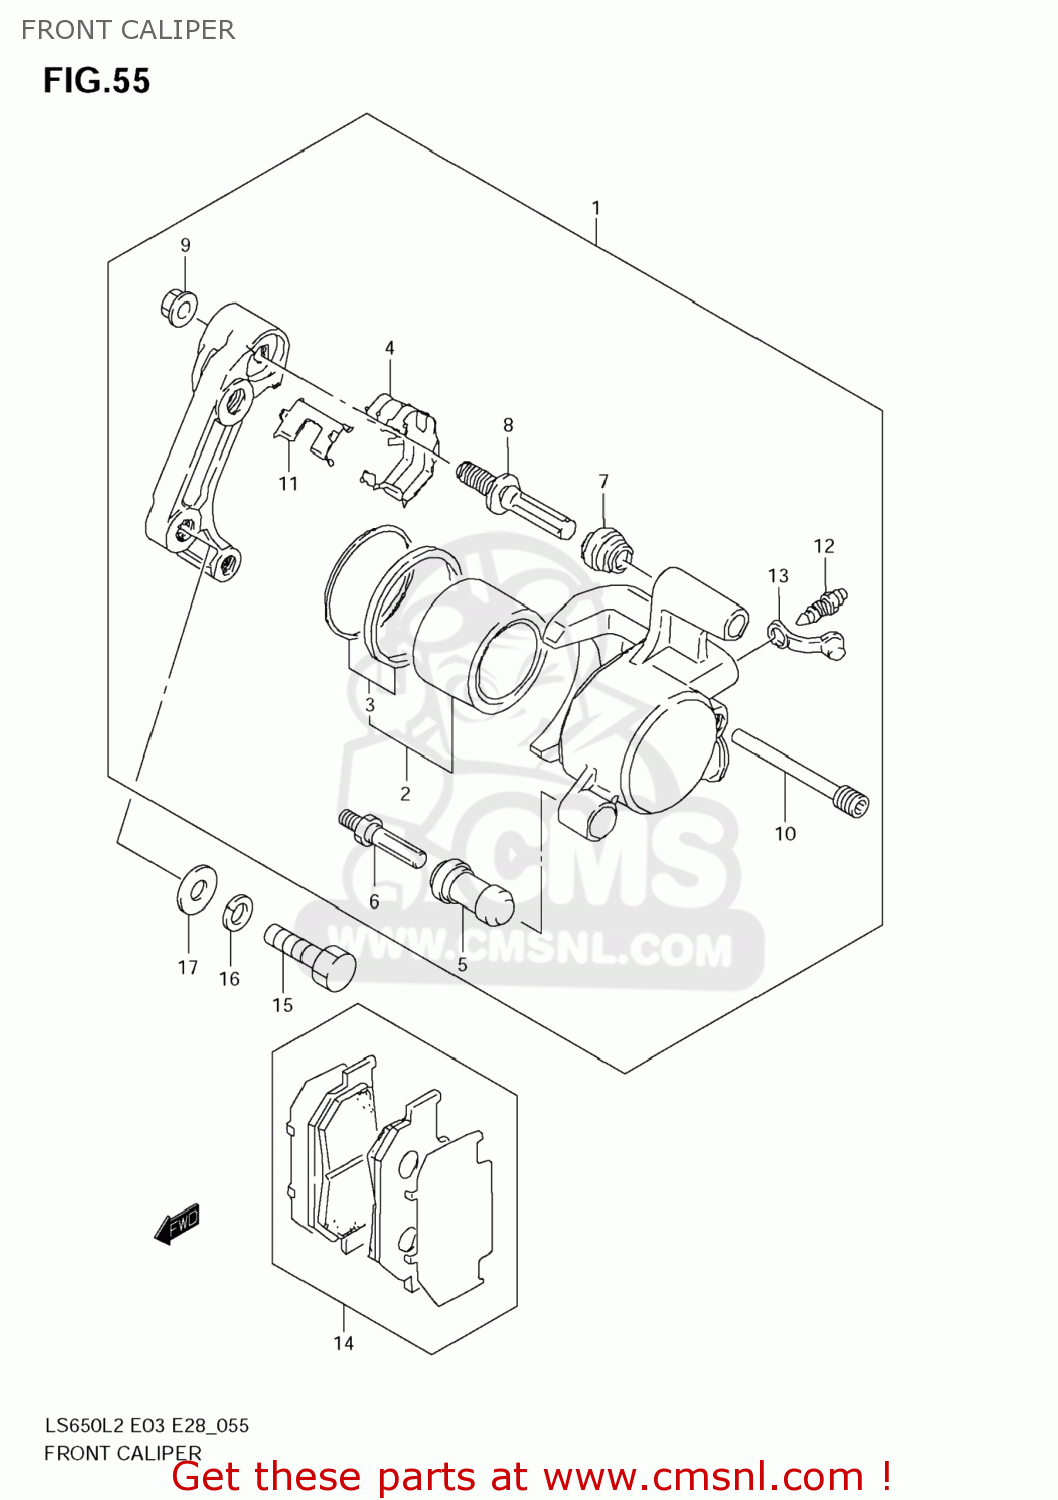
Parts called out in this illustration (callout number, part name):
1	CALIPER ASSY,FR
2	PISTON SET
3	SEAL SET,PISTON
4	SPRING
5	BOOT
6	PIN,BOLT
7	BOOT
8	PIN,SLIDE
9	NUT,SLIDE PIN
10	PIN,HANGER
11	RETAINER
12	BLEEDER
13	CAP,BLEEDER
14	PAD SET (NAS)
15	BOLT(10X38)
16	WASHER,LOCK
17	WASHER
